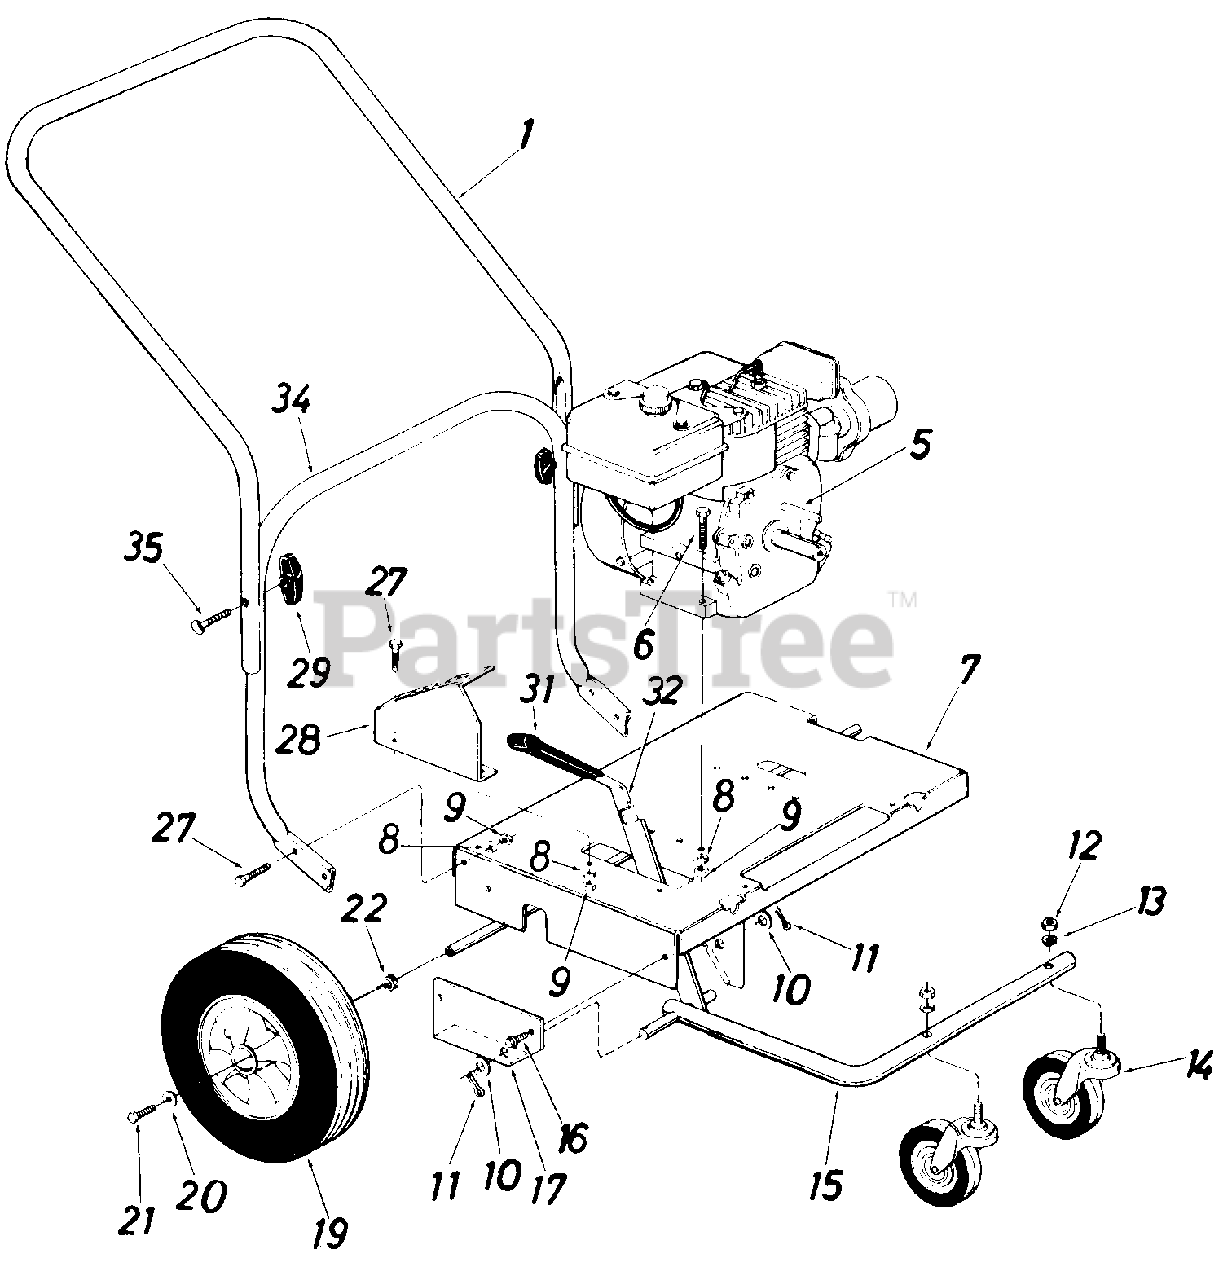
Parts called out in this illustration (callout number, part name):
1	Upper Handle
5	Sq. Key 1/4" x 2.00" Lg. *
6	Hex Bolt 5/16-18 x 1.50" Lg.*
7	Engine Mounting Frame Ass'y.
8	L.-Wash. 5/16" I.D.*
9	Hex Nut 5/16-18 Thd.*
10	Fl.-Wash. .63" I.D. x 1.25" O.D.
11	Cotter Pin 5/32" Dia. x 1.25" Lg.*
12	Hex Nut 1/2-13 Thd.*
13	L.-Wash. 1/2" I.D. *
14	Swivel Caster Wheel 5" Dia. x 1.25"
15	Caster Arm Ass'y.
16	Hex Wash. Hd. "AB" Tap Scr. 5/16" x .75"
20	Fl.-Wash. 34" I.D. x .87"O.D.
21	Hex Locking Bolt 5/16-24 x.62" Lg.
22	Fl.-Wash.
27	Hex Bolt 5/16-18 x .75" Lg. *
28	Index Plate
29	Hand Knob
31	Fl.-Grip Vinyl
32	Height Adj. Handle
34	Lower Handle
35	Cariage Bolt 5/16-18 x 2.0" Lg.
14529-0638	BRACKET-CASTER ARM - MTD/TROY-BILT RED (0638)
14529-0691	BRACKET-CASTER ARM - BLACK JACK (0691)
